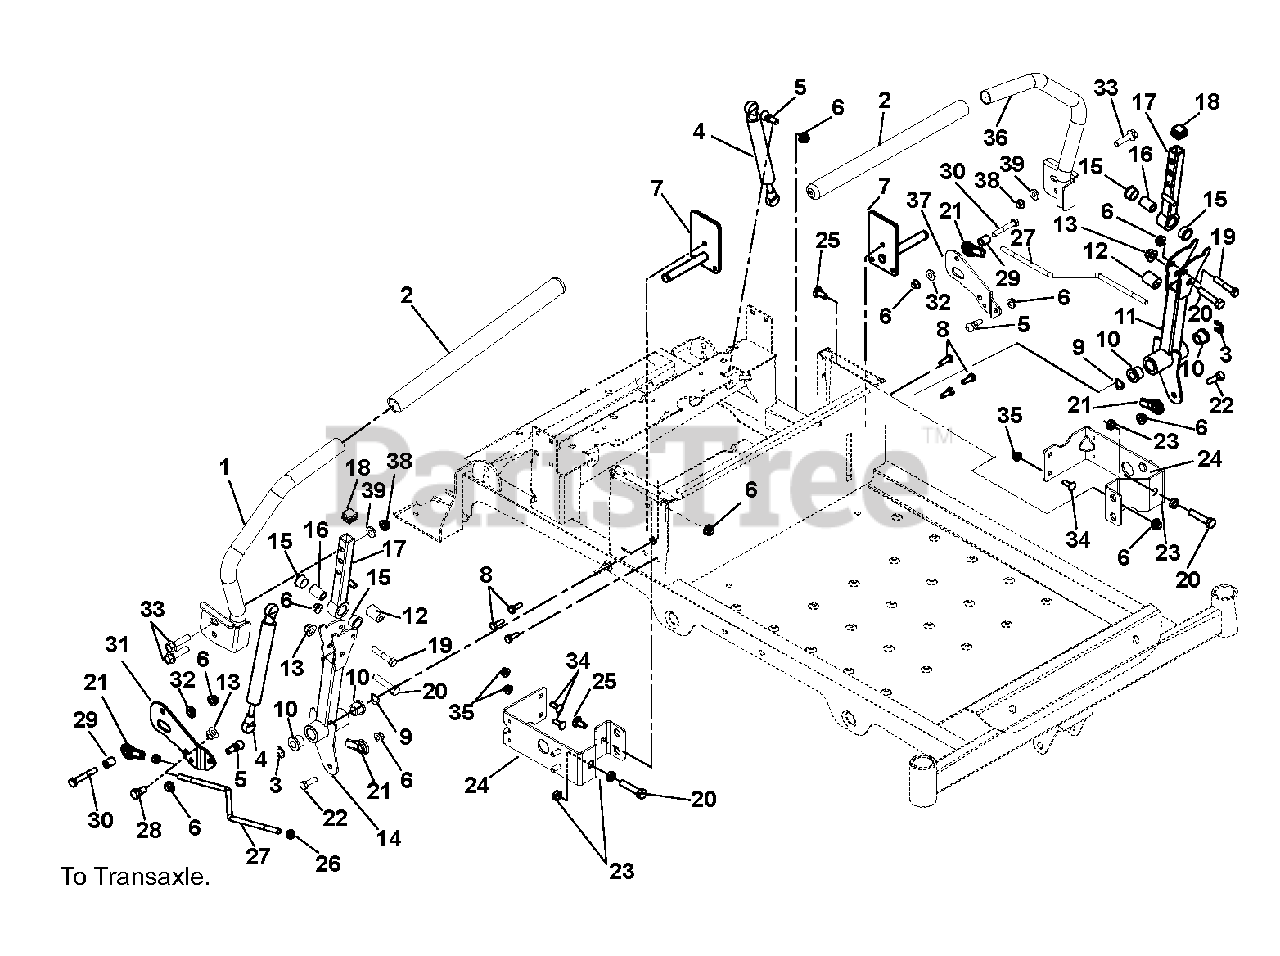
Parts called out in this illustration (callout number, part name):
1	Weldment, Steering Handle Right Hand
2	Grip, Handlebar 15" Foam
3	Ring, Retaining External .438 x 1.00 x 0.83
5	Stud, Ball
6	Nut, .31-18 Flange
7	Weldment, Steering Shaft
8	Screw, Tapping .25-20 x .50 Hex Washer Head
9	Washer, Wave
10	Bushing, Flanged
11	Weldment, Lower Control Arm
12	Bushing, Eccentric
13	Nut, .38-16 Nyloc Flange
14	Weldment, Lower Control Right Hand
15	Bushing, Flanged
16	Spacer, .375 x .625 x .970
17	Weldment, Upper Control Arm
18	Cap Plug, Square
19	Bolt, Hex .31-18 x 1.75
20	Bolt, Hex .375-16 x 1.75
21	Alignaball, 5/16 RH Thread
22	Bolt, Hex .31-18 x 1.00
23	Nut, Hex Jam .375-16
24	Bracket, Speed Adjustment/Seat Pivot
25	Bolt, Round Head Square Neck .31-18 x .75
26	Nut, Jam, .31-24
27	Wireform, Steering Link
28	Bolt, Hex .38-16 x .75
29	Spacer, .328 x .500 x .625
30	Bolt, Hex .31-18 x 2.00
31	Plate, Dampener Right Hand
32	Bushing, Flanged
33	Bolt, Serrated Hex Flange Washer Head .375-16 x 1.25
34	Bolt, Round Head Square Neck .25-20 x .75
35	Nut, Locking Nylon Flange .25-20
36	Weldment, Steering Handle Left Hand
37	Plate, Damper Left Hand
38	Nut, Locking Center Jam .375-16
39	Washer, Flat Steel .406 x .812 x .065
